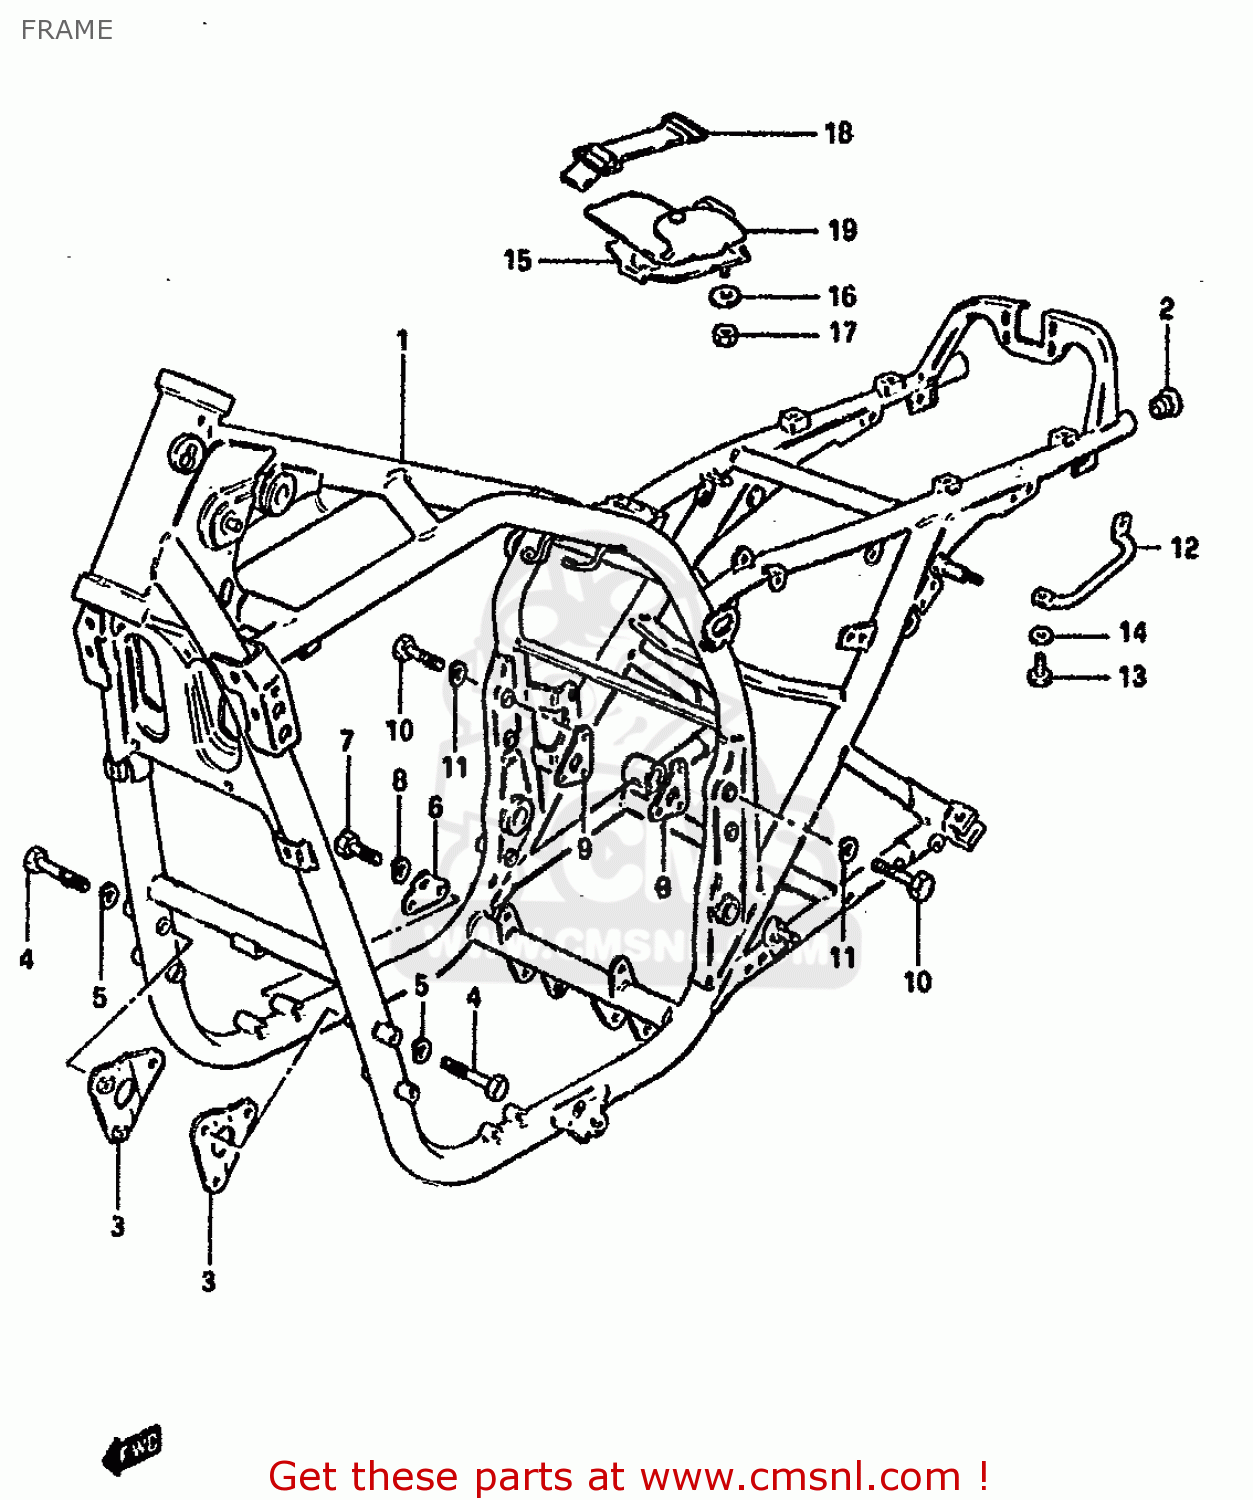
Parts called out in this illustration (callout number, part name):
1	FRAME (SILVER)
2	CAP(OD:26)
3	PLATE,ENGINE MOUNTING
4	BOLT(8X65)
5	LOCK WASHER
6	PLATE,ENG MTG NO.2
7	BOLT 8X16
8	LOCK WASHER
9	PLATE,ENG MTG NO.4
10	BOLT
11	LOCK WASHER
12	GRIP,STAND
13	BOLT
14	WASHER
15	HOLDER,TOOL
16	WASHER(6.5X30X1.6)
17	NUT
18	BAND
19	TOOL SET
